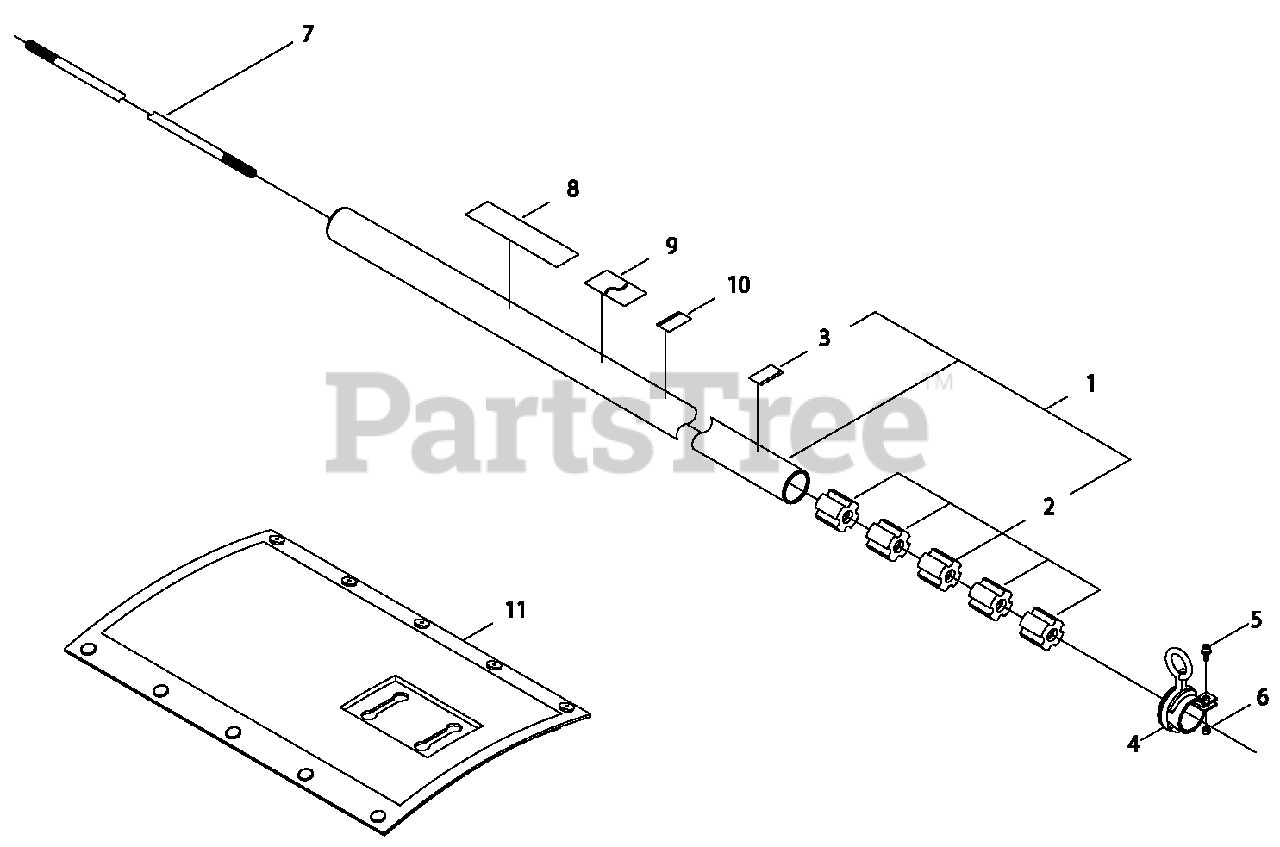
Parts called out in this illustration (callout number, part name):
1	MAIN PIPE ASSY
2	BUSHING
3	LABEL - ALIGNMENT
4	HANGER ASSY
5	SCREW - 5X12
6	NUT - 5
7	DRIVESHAFT
8	LABEL - SHINDAIWA PROFESSIONAL
9	LABEL - CAUTION
10	LABEL - HANDLE LOCATION
11	PROTECTOR
